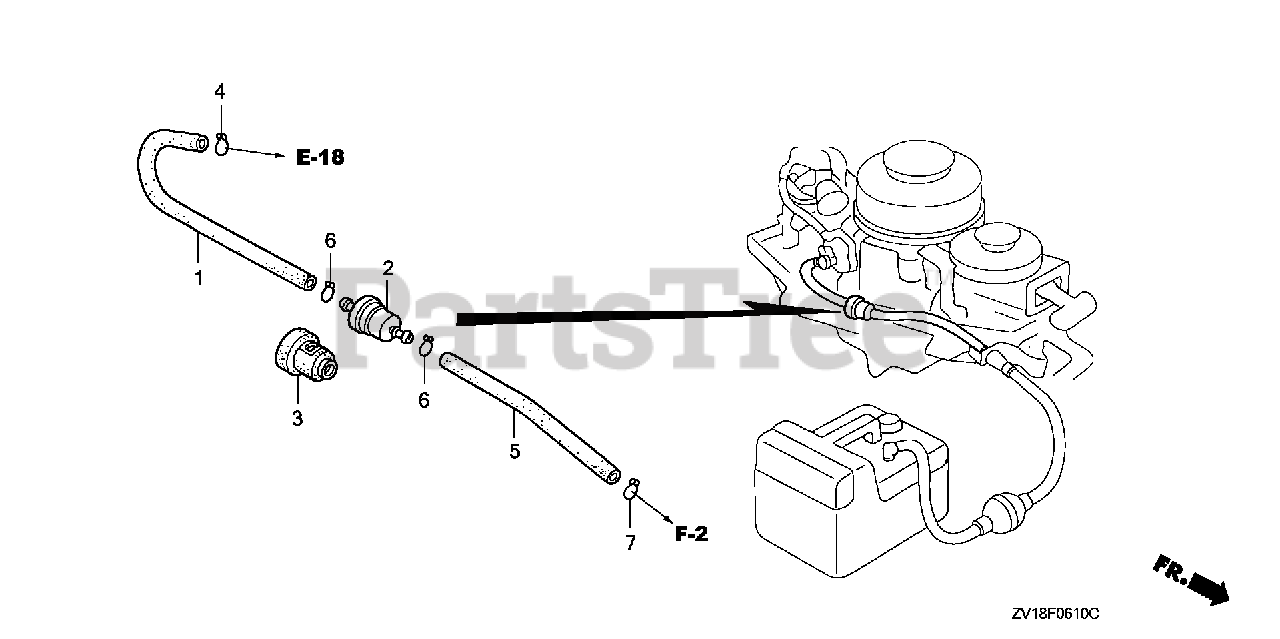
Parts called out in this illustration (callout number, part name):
1	TUBE, FUEL (4.5MM) (ENGINE NO.)
1	TUBE B, FUEL (ENGINE NO.)
2	FILTER, FUEL
3	SUSPENSION, STRAINER
4	CLIP, TUBE (B8)
5	BULK HOSE, FUEL (4.5X3000) (Honda Code 5137104). (4.5X140)
5	TUBE A, FUEL (ENGINE NO.)
6	CLIP, TUBE (B8)
6	CLIP, TUBE (B10)
7	CLIP, TUBE (B8)
7	CLIP, TUBE (ENGINE NO.)
